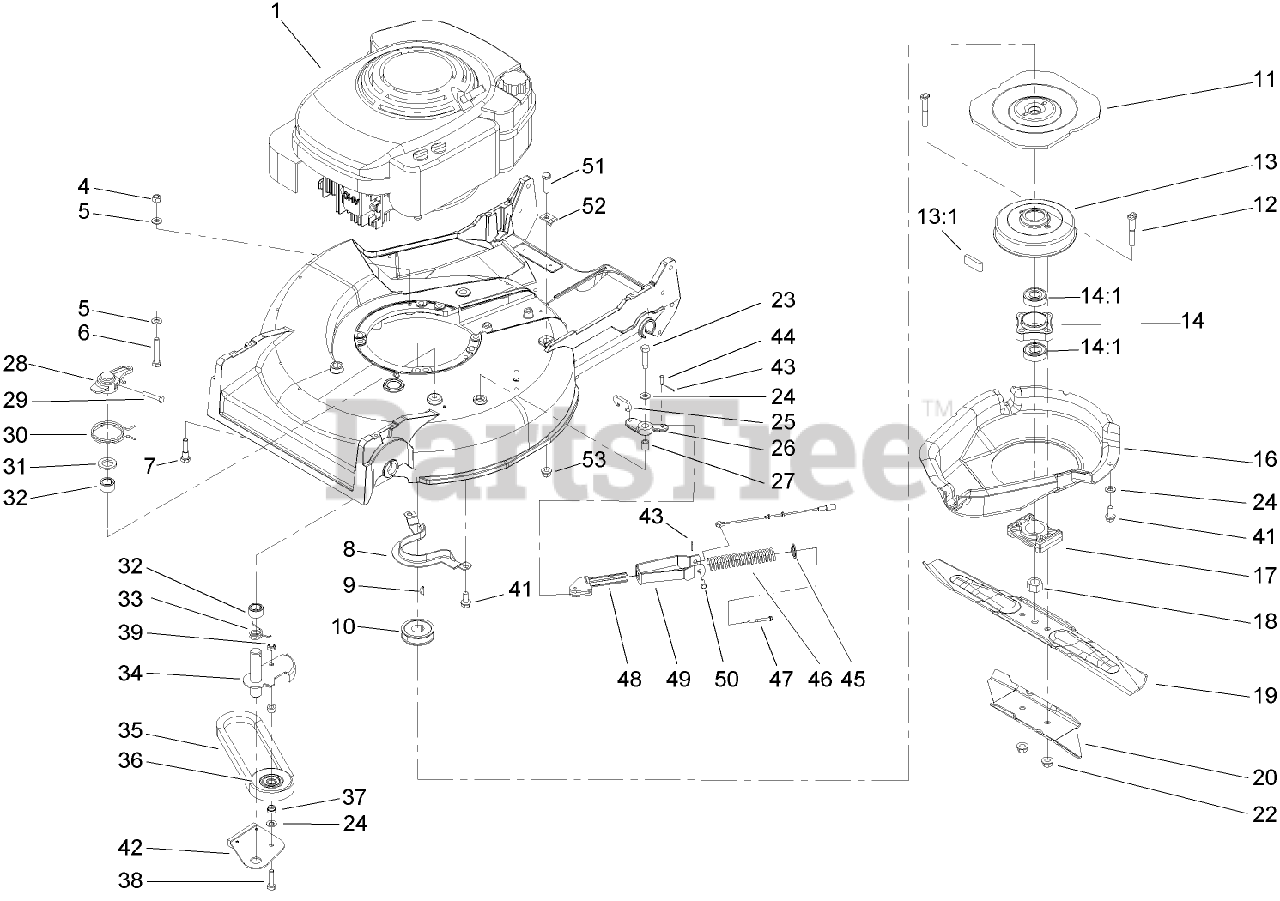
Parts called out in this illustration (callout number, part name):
1	Loose Parts Package
4	NUT-LOCK, NI
5	WASHER-PLAIN
6	SCREW-HH
7	SCREW-SHOULDER
8	BRACKET-GUIDE, BELT
9	KEY-WOODRUFF
10	PULLEY-DRIVER
11	FLYWHEEL - BBC
12	BOLT-BLADE
13	BRAKE DRUM ASM
13:1	DAMPENER-VIBRATION
14	HUB ASM
16	SHIELD
18	NUT-BLADE
19	BLADE-21 INCH
20	STIFFENER-BLADE
22	NUT-LOCK
23	SCREW-HH
24	WASHER-PLAIN
25	LINK-CONTROL
26	BELLCRANK
27	SLEEVE-BELLCRANK
28	LEVER
29	SCREW-HH
30	SPRING-TORSION
31	WASHER
32	BEARING
33	SPRING-TORSION
34	ARM-IDLER
35	V-BELT
37	SPACER-PULLEY, IDLER
38	SCREW-HH
39	NUT-LOCK, NI
41	SCREW-HWHTF
43	PIN-COTTER
44	PIN-SPRING
45	RETAINER-SPRING
46	SPRING
47	SCREW-HWHTF
48	GUIDE-SPRING
49	BRACKET-SPRING
50	PIN-CABLE
51	SCREW-HH
52	CLAMP-CABLE
53	NUT-LOCK, NI
